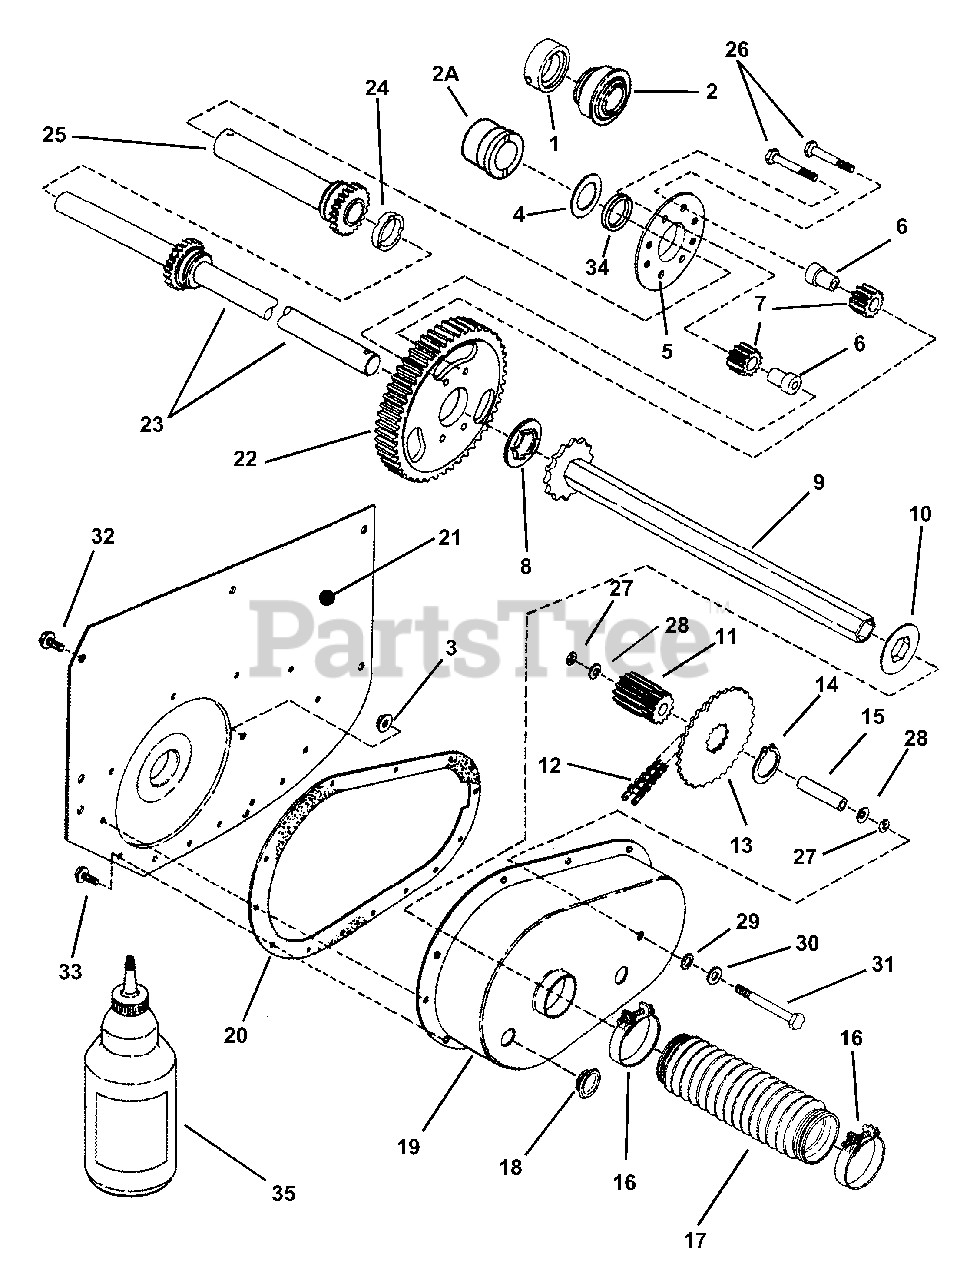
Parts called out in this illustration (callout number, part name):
1	COLLAR, Lock
2	BALL BEARING, Axle (Right Hand Fender)
2A	BEARING, Axle (Right Hand Fender)
3	NUT, 5/16-24 Hex Flange Lock
4	WASHER, Thrust
5	PLATE, Differential
6	SPACER, Pinion
7	GEARS, Differential Pinion
8	WASHER, Thrust
9	ASSEMBLY, Drive Hex Tube
10	WASHER, Hex Nylon Splash
11	GEAR, 11 Teeth-10 Pitch
12	CHAIN, 46 Pitch (No. 35)
13	SPROCKET
14	RING, External Retaining
15	SPACER
16	CLAMP, Boot
17	BOOT, Oil Seal
18	PLUG, Oil Fill & Check
19	CASE, Transmission
20	GASKET, Transmission Case
21	FENDER, Right Hand
22	GEAR, 63 Teeth-10 Pitch
23	AXLE, Long
24	SPACER
25	AXLE, Short
26	SCREW, 5/16-24 x 1-5/8" Hex Cap Special Lock
27	O-RING, 5/16"
28	WASHER, 5/16" Belleville
29	WASHER, 5/16" External Tooth Lock
30	WASHER, 5/16" Flat
31	BOLT, 5/16-24 x 2-5/8" Idler
32	SCREW, 5/16-18 x 5/8" Hex Washer Self-Tap
33	SCREW, 1/4-20 x 5/8" Hex Washer Self-Tap
34	SPACER, Short Axle
35	GREASE, Transmission
